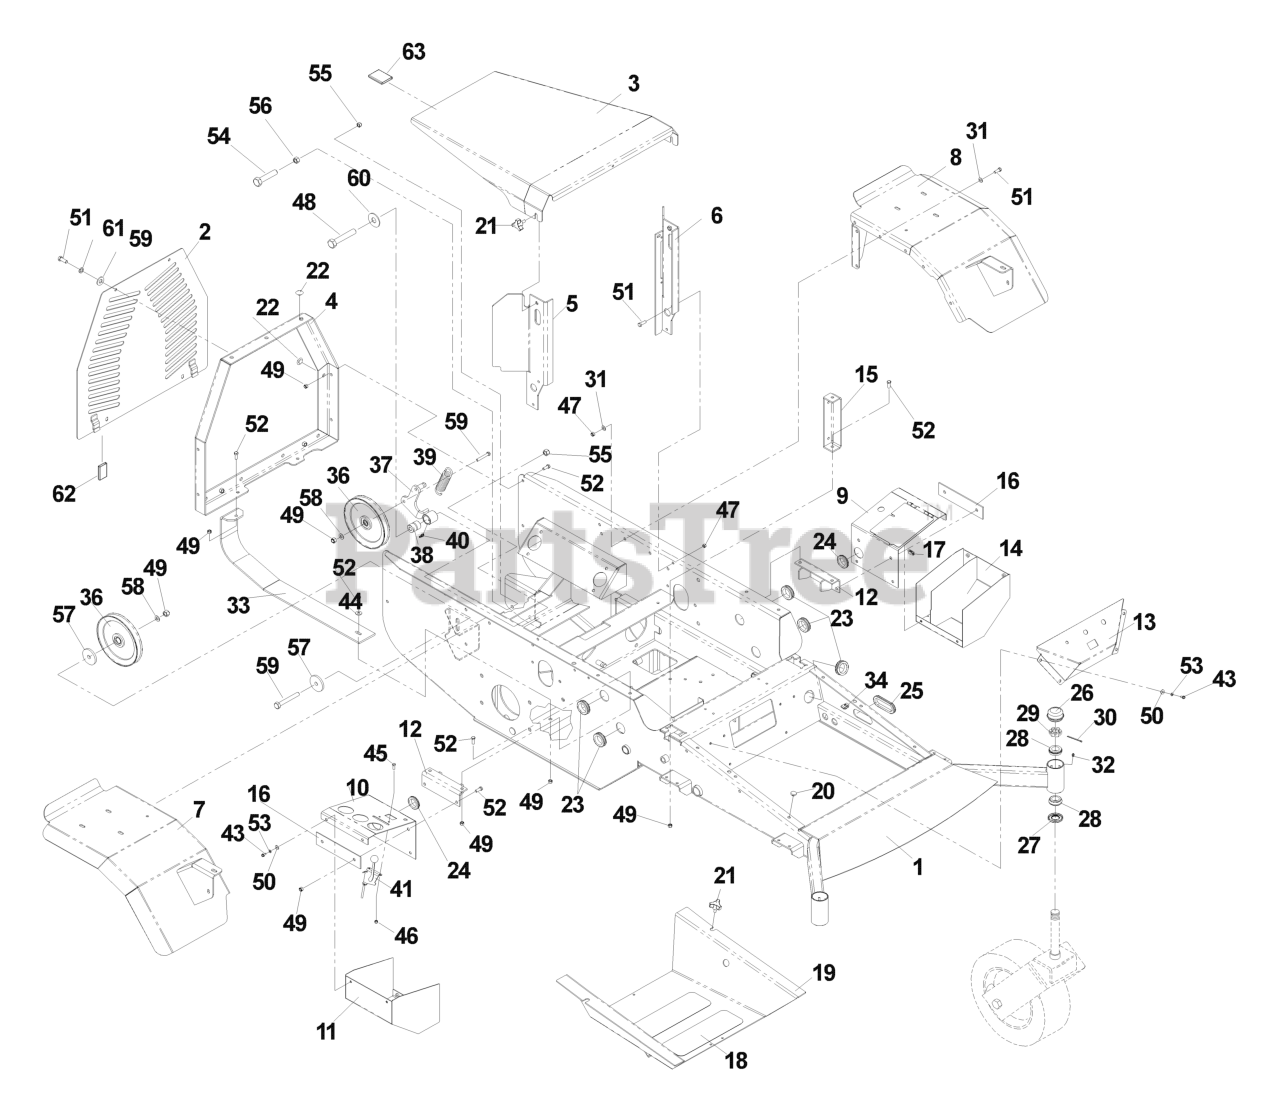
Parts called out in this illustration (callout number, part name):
1	FRAME W/DECALS
2	PANEL W/ DECALS
3	HOOD ORANGE
4	REAR FRAME
5	SUPPORT WLDMT, RT
6	SUPPORT WLDMT, LT
7	FENDER WELDMT, RH
8	FENDER WELDMT, LH
10	CONSOLE TOP-PAINTED
11	CONSOLE BOTTOM
12	MTG ANGLE WELDMT
13	CENTER CONSOLE WELDMENT
14	BOTTOM CONSOLE
15	SUPPORT WELDMENT
16	BLACK-STIFFNER-PAINTED
17	MAGNETIC LATCH
18	ANTI-SKID PAD
19	FOOT PLATE WIDMT
20	GROMMET, BUMPER
21	KNOB W/STUD
22	GROMMET BUMPER
26	GREASE CAP
28	TAPERED ROLLER BRG
29	NUT 1"C HEX SLOTTED
30	COTTER PIN 1/8 X 2
31	FLAT WASHER 5/16 SAE
32	ZERK
33	SKID PLATE
34	U-CLIP 5/16-18 NUT RETAINER
37	ARM WELDMENT
40	ZERK
41	THROTTLE CONTROL W/BALL KNOB
43	SCREW 1/4 X 5/8
44	WASHER 3/8 FLAT
45	HCS #10-24 X 1/2
46	NUT 10-24 NYLOC
47	NUT 5/16 NYLOC
48	HEX SCREW 1/2-13 X 2.5" GR 5
49	NUT 3/8-16 NYLOC
50	WASHER 1/4 FLAT
51	HCS 5/16C X 1
52	HCS 3/8-16X1.GRD.5.ZD
53	LOCKWASHER 1/4"
54	HCS 1/2-13X2 GR 8
55	NUT 1/2-13 HEX NYLOC ZD
56	NUT HEX 1/2
57	SPINDLE WASHER
58	WASHER 3/8 SAE FLAT
59	WASHER 5/16 FLAT
60	WASHER 1/2 FLAT
61	WASHER.LOCK.HVY.HLCL.SPR.5/16
